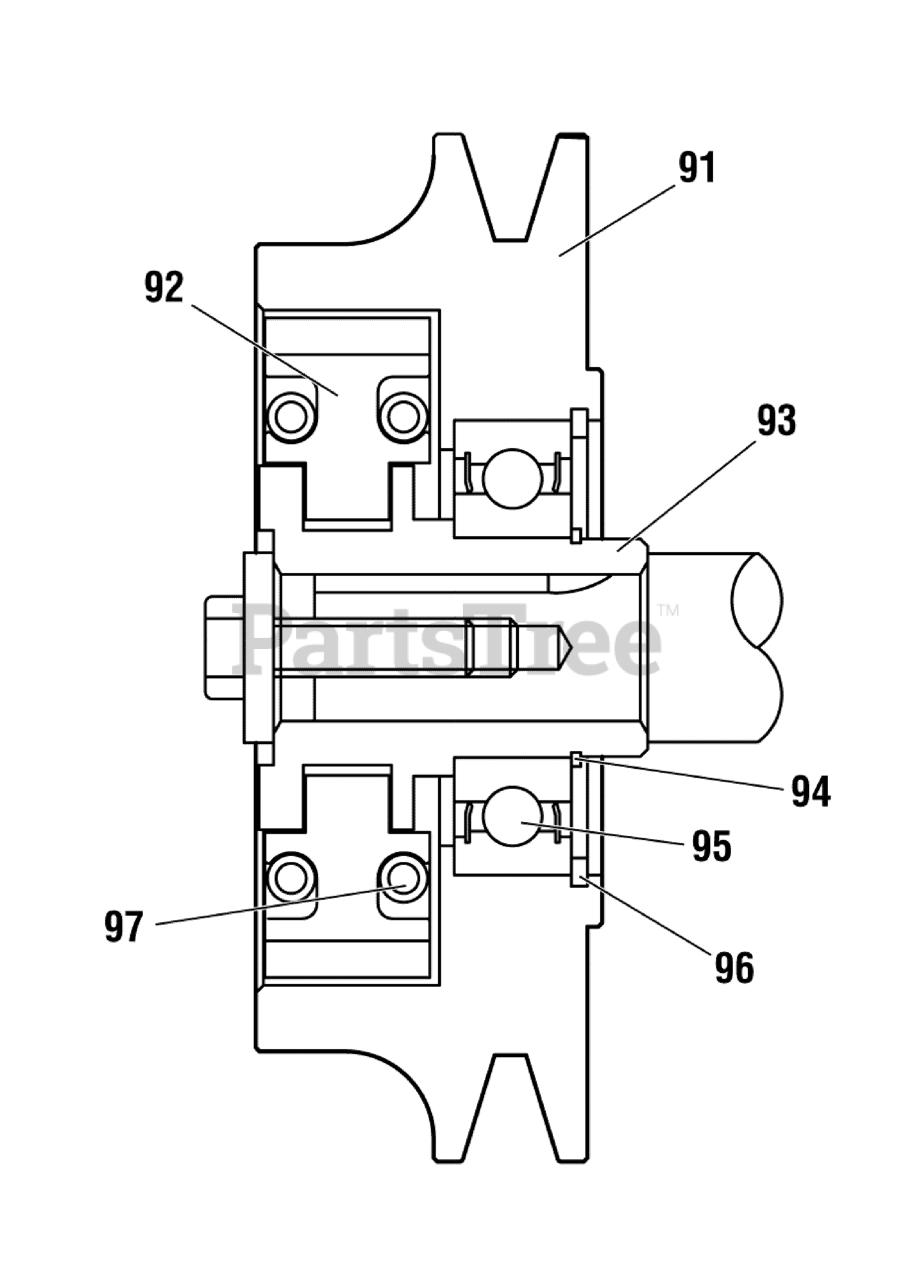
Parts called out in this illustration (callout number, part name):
91	CLUTCH, Outer
92	CLUTCH CORE, ZG270-500
93	FRICTION PLATE, Clutch
94	RING SHIELD,30
95	BEARING, 6206-2RS
96	CIRCLIP, Internal, 62
97	SPRING, Clutch, T8MA (GB4358)
